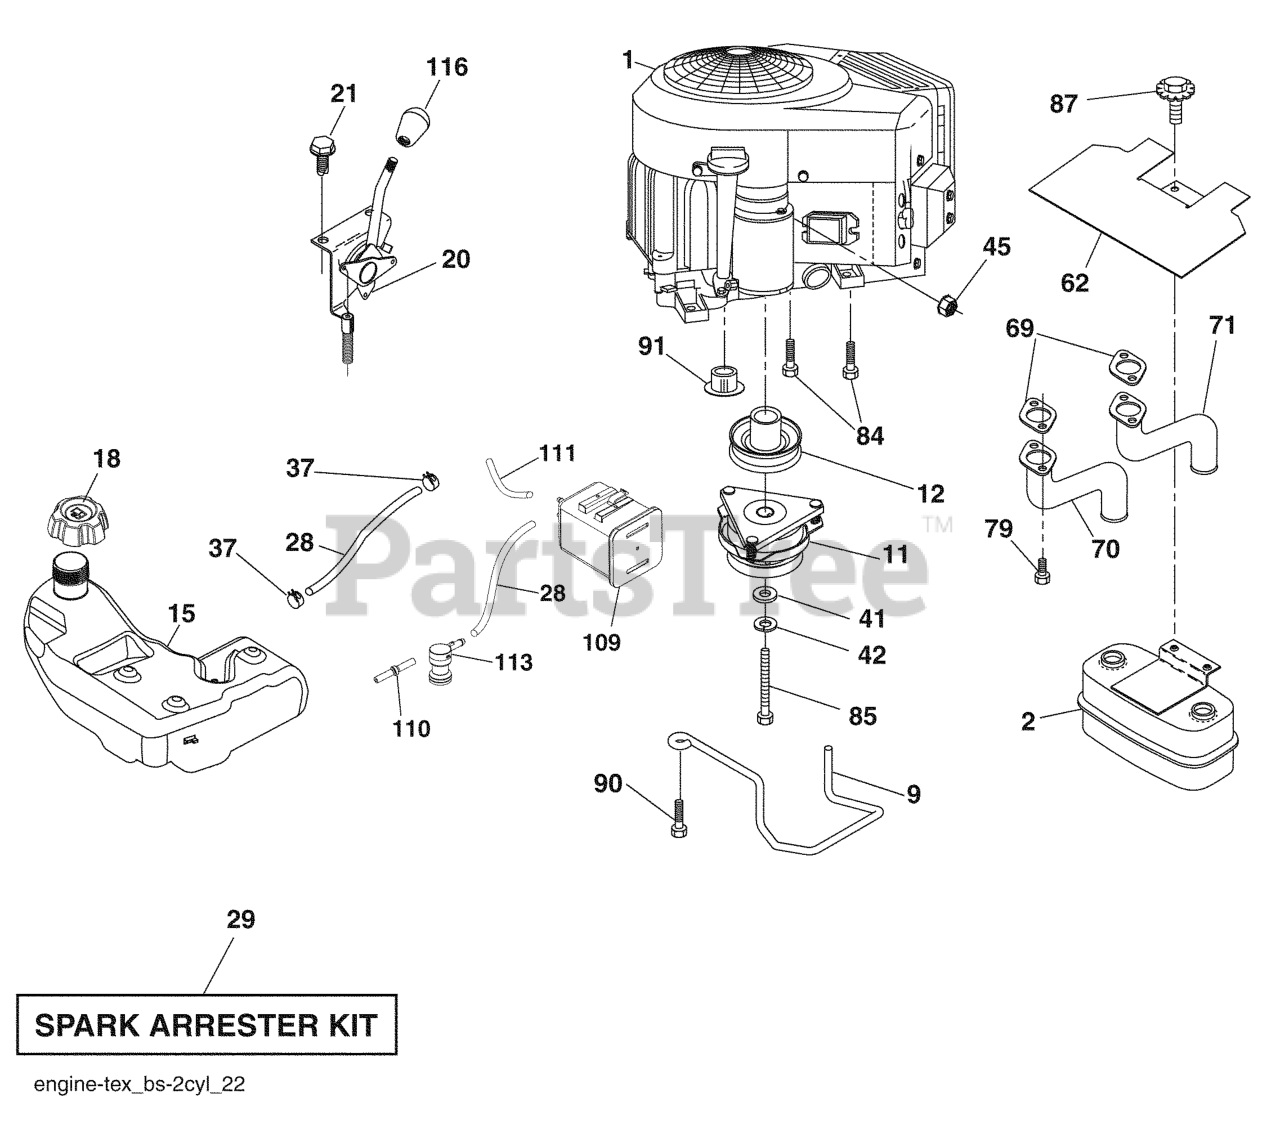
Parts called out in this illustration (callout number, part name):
2	MUFFLER.TWIN.CYL.LOW.TONE
9	KEEPER.BELT.ENGINE.4.2
11	CLUTCH.ELECTRIC.LT.48"*
12	PULLEY.ENGINE.TUFFTORQ
15	TANK.ASM.FUEL.3GA.CARB
18	CAP ASM
20	CONTROL THROTTLE/CHOKE
21	SCREW.#10 X 0.750.BOS
28	LINE.FUEL.64"REAR.EMIS
29	KIT.SPARK ARRESTOR 794945 B&S
37	HOSE CLAMP
42	LOCKWASHER
45	NUT
62	RP SHIELD HEAT MUFFLER
69	GASKET.MUFFLER
70	RP.EXHAUST.TUBE.LH.BS/TWIN
71	EXHAUST.TUBE.RH.BS/TWIN
79	SCREW.SOCKET.HEAD.5/16-18
84	SCREW.3/8-16
85	BOLT HEX 7/16-20X4-1/4"
87	BOLT 5/1618UNC X 3/4 W/ SEMS
90	SCREW 3/8-16X1
91	BUSHING.1.375OD
109	CANNISTER, CARBON
110	VALVE.ASM.ANTI-SLOSH
111	RP PURGE LINE
113	VALVE.SLANT.CARTRDG.90 DEG.TEX
116	RP KNOB SOFT TOUCH
